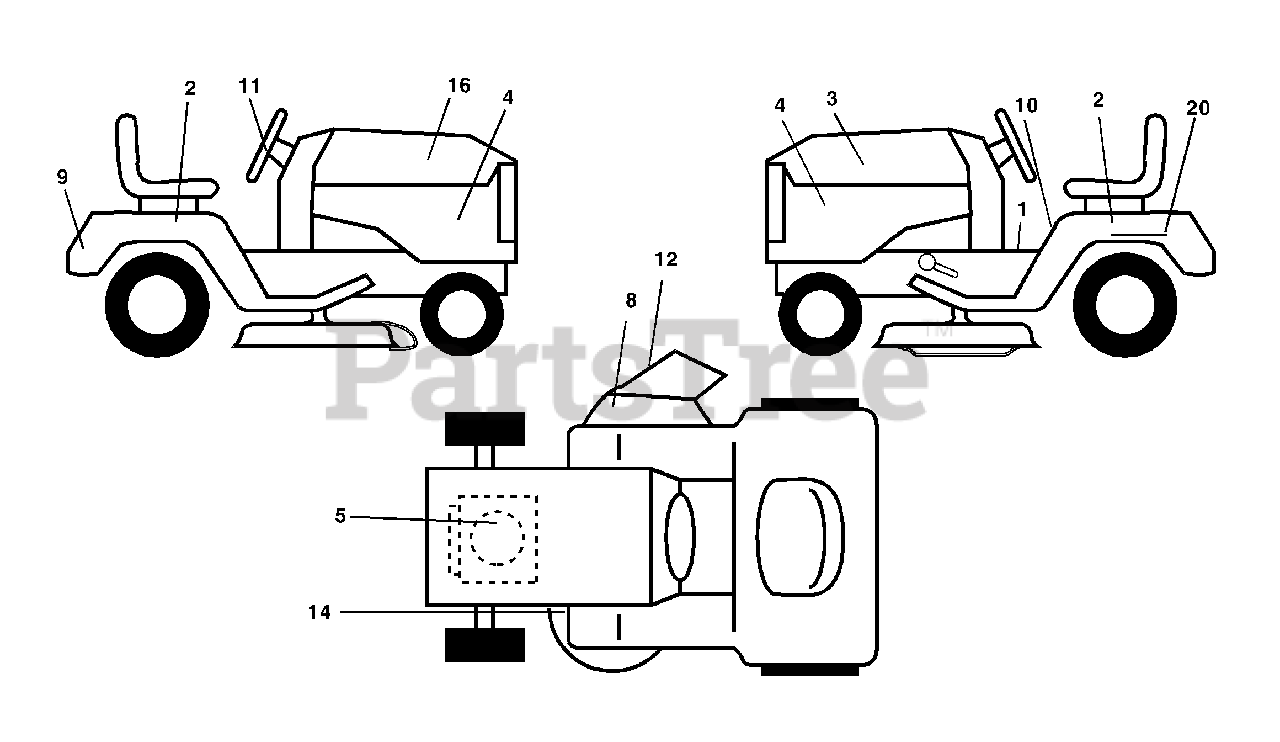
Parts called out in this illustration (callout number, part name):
1	Decal Oper
2	Decal Fender Auto
3	Decal Hood LH
4	Decal Side Panel Logo
5	Decal HP Engine
8	Decal Deck "B" 42"
9	Decal Fender Logo
10	Decal Fender Danger E/F
11	Decal Ins Strg Whl
12	Decal Mower Warn Keep Hand Away
14	Decal V-Belt Schematic
16	Decal Hood Rh
20	Decal Bat Dan/Psn
20	Decal By Pass Lt Hydro
